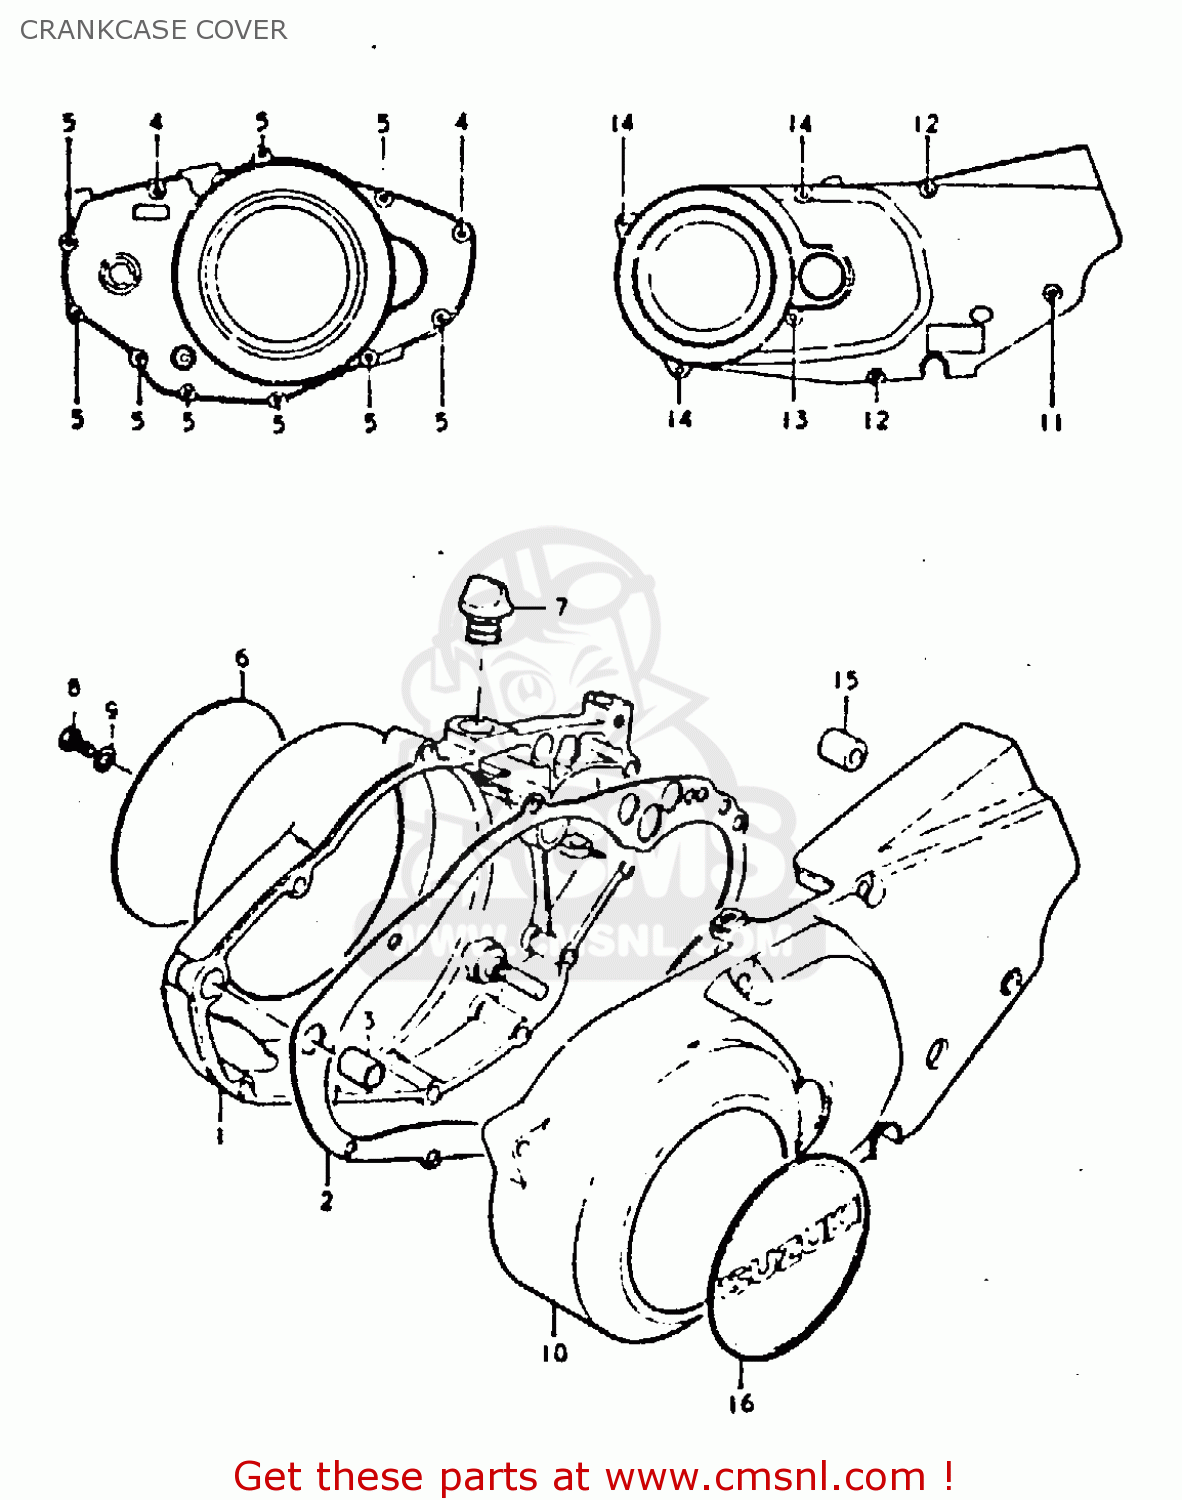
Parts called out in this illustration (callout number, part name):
1	COVER, CLUTCH
2	GASKET, CLUTCH COVER (MCA)
3	PIN
4	SCREW
5	SCREW (6X35)
6	EMBLEM,CLUTCH COVER
7	PLUG
8	SCREW(6X10)
9	GASKET(6.2X11X1) (NAS)
10	COVER, MAGNETO
11	SCREW
12	SCREW
13	SCREW
14	SCREW 6X30
15	CUSHION (4.5*8.5*14)
16	EMBLEM,COVER
